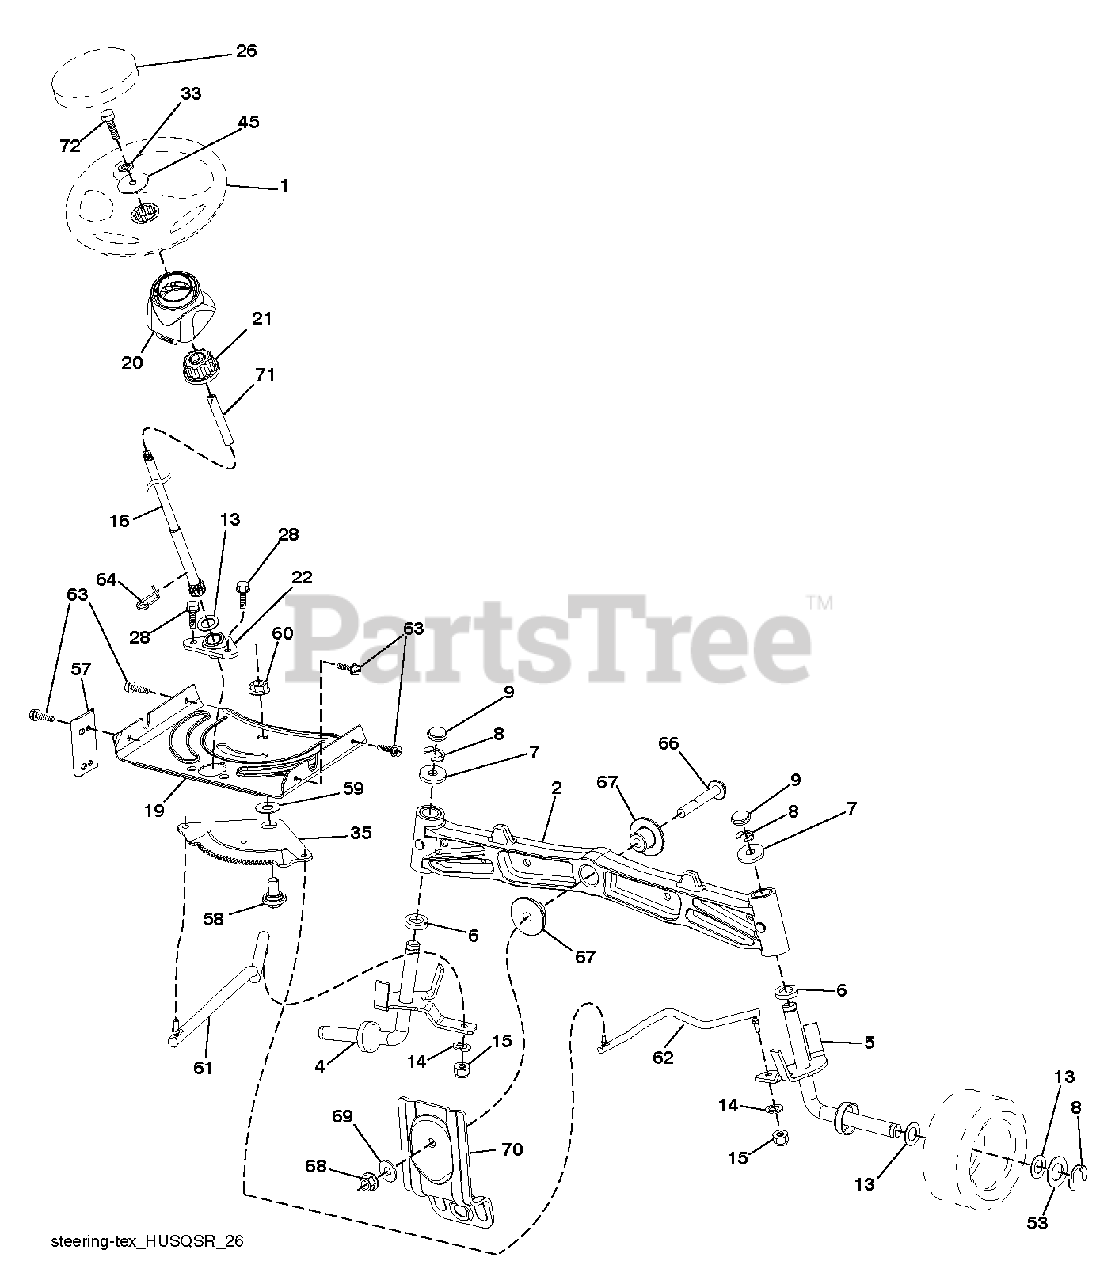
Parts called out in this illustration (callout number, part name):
1	WHEEL.STEERING.PREM.2.BLK
2	AXLE.CAST.IRON
4	SPINDLE.WELDED.LH.15"TEX
5	SPINDLE.WELDED.RH.15"T
8	RING CLIP
9	CAP.SPINDLE
14	WASHER, LOCK 3/8
15	NUT CROWNLOCK 3/8-24
16	SHAFT.STEER.3/4.PLATED.TEX
19	PLATE.STEER.DDL.NLT/NG
20	BOOT STEERING BLACK
21	ADAPTER, WHEEL STNG..
22	STEERING.SUPT.LOWER.
26	INSERT.CAP.STRG.WH.BLACK
28	SCREW, 3/8-16X3/4
33	LOCKWASHER
35	GEAR.SECTOR.PLATE.DDL.
45	WASHER.11/32
53	WASHER.HARDENED
57	BRACKET.UPSTOP.TEX
58	BOLT.SHOULDER.SECTOR.P
59	WASHER.THURST.SECTOR.S
60	NUT FLANGE LOCK 5/8-11
61	DRAGLINK.LH.BALLSTUD.D
62	DRAGLINK.RH.BALLSTUD.D
63	SCREW
64	RETAINER.CLIP.SPRING.S
66	BOLT HEX FGHD 7/16-14 X 3 SERR
67	BUSHING.PM.FRONT AXLE
68	NUT.LOCK.FLANGE.7/16
69	WASHER.1.5X.505X.118
70	BRKT.DECK.SUSPENSION.F
71	SHAFT.EXTEN.STRG.SPLINE
72	BOLT 5/16-18 X 4 W/PATCH
